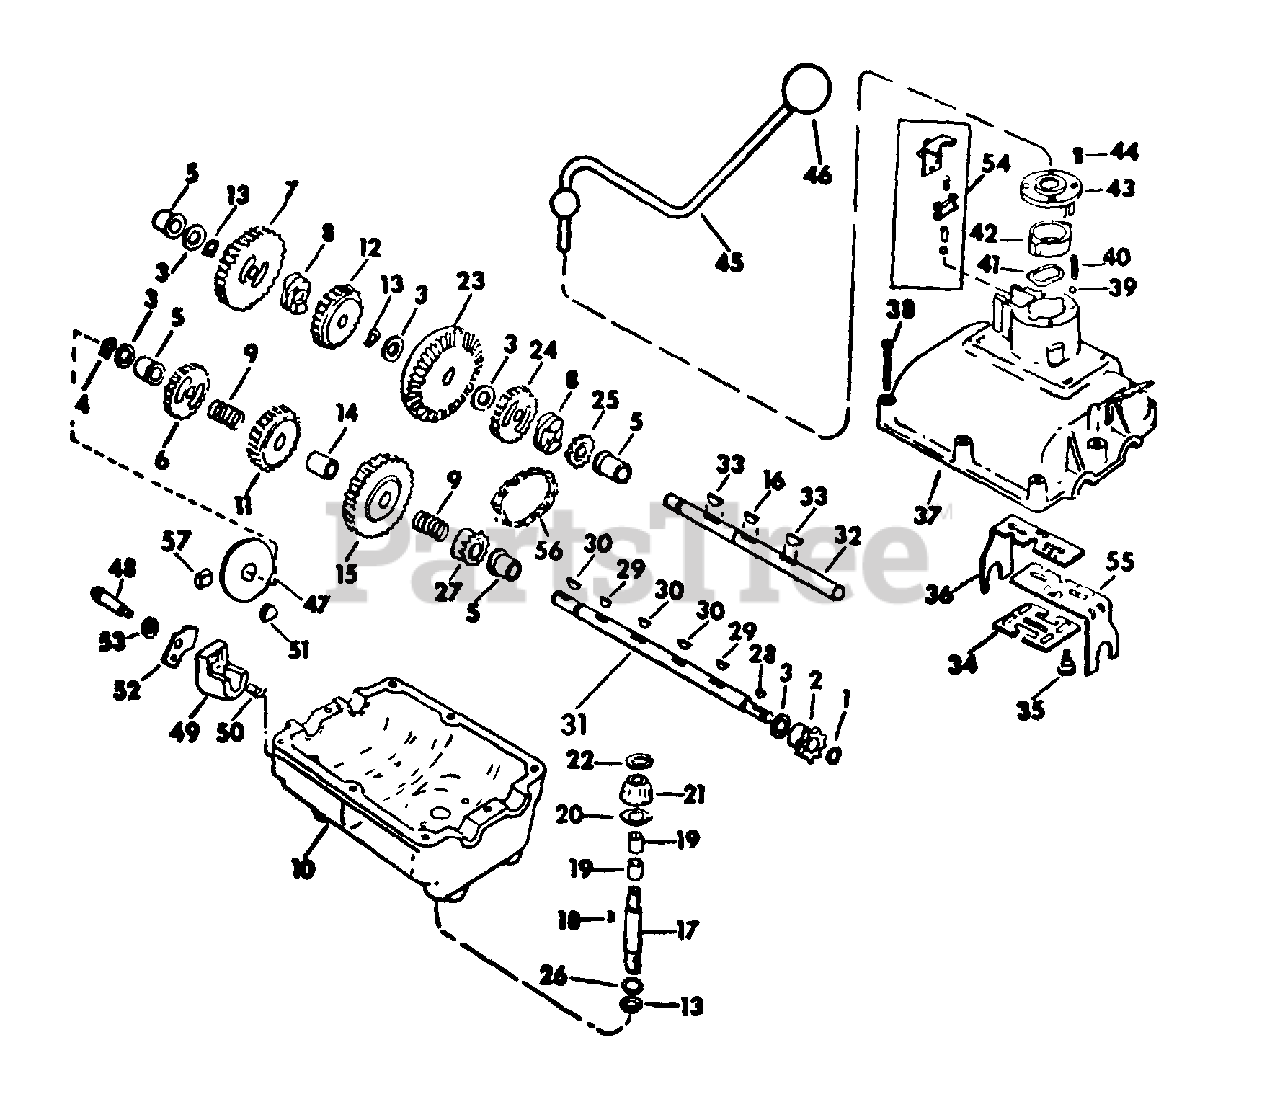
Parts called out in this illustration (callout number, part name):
1	RING, .461 INV EXT RET
2	SPROCKET, 8 T
3	WASHER, PLAIN .030
3	WASHER, PLAIN .040
3	WASHER, PLAIN .050
3	WASHER, PLAIN .036
3	WASHER, PLAIN .026
3	WASHER, PLAIN .046
3	WASHER, PLAIN .020
4	E-RING, .480 EXT RET
5	BEARING, FLANGE
6	GEAR, SPUR -20 T
7	GEAR W/SPACER, SPUR -30 T
8	COLLAR, CLUTCH
9	SPRING, COWPRESSION
10	HOUSING, LOWER
11	GEAR W/SPACER, SPUR -25 T
12	GEAR W/SPACER, SPUR -25 T
13	RING, .579 EXT RET
15	GEAR, SPUR -30 T
16	KEY, 3/16 X 3/4 WOODRUFF 9
17	SHAFT KIT, INPUT
18	KEY, 3/32 X 1/2 WOODRUFF 2
19	BEARING, NEEDLE
20	WASHER, THRUST .093
21	PINION, BETHEL -16 T
22	RING, .461 EXT RET
23	GEAR, BEVEL -42 T
24	GEAR, SPUR -20 T
25	SPROCKET, SPECIAL -12 T
26	WASHER, .656 X 1.000 X .054 PLN
27	SPROCKET, SPECIAL -12 T
28	KEY, WOODRUFF NO. 4 SPECIAL
29	KEY, 1/8 X 1/2 WOODRUFF 3
30	KEY, 3/16 X 5/8 WOODRUFF 61
31	SHAFT, OUTPUT
32	SHAFT, W/RING, IH-269174-R1, DRIVE
33	KEY, HI-PRO SPECIAL
34	PLATE, LOCK-OUT
35	SCREW, SHOULDER
36	FORK, SHIFTER LH
37	HOUSING, UPPER
38	SCREW, TAPPING
39	BALL, 3/16 GRADE 25 METAL
40	SPRING, DETENT
41	WASHER, WAVE
42	INSERT, NYLON
43	COVER, NYLON
44	SCREW, 10-24 X 1/2 C-Z CR-REC-PAN-HD TAP
45	SHIFTER HANDLE ASSY
46	KNOB, SHIFTER
48	BOLT, SHOULDER
49	KIT, BRAKE ASSY
50	SPRING, COMPRESSION
51	PUCK, FRICTION
52	LEVER ASSY, ACTUATING RH
53	WASHER, PLAIN .015
53	WASHER, PLAIN .006
54	KIT, SWITCH ASSY
55	FORK, SHIFTER RH
56	CHAIN, ROLLER
57	PUCK, FRICTION
